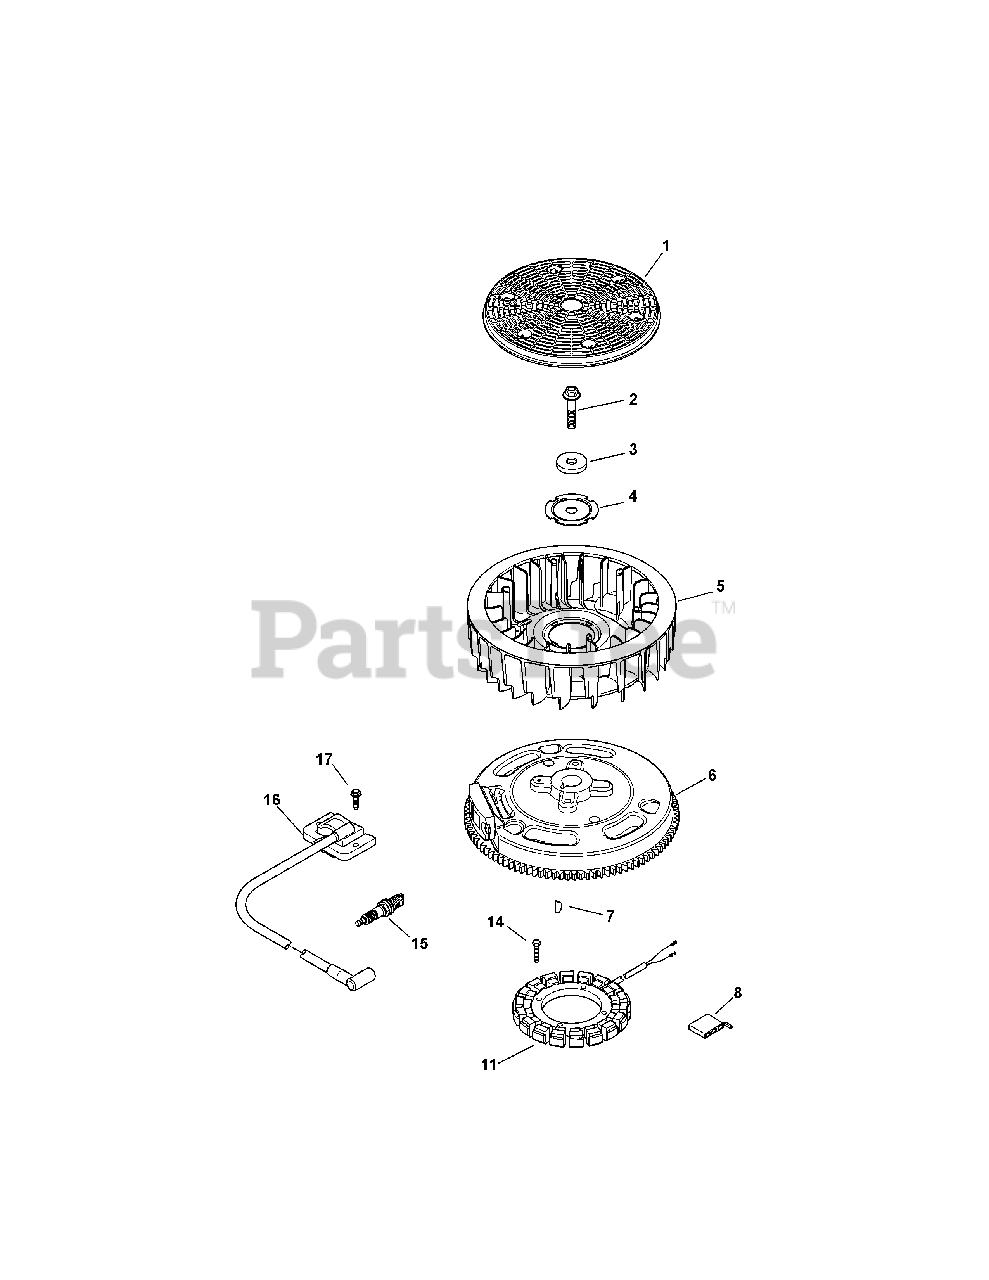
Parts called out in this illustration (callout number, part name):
2	Flg. Screw, M 10 X 1.5 X 45
3	Flat Washer, 13/32
4	Fan Mounting Plate
5	15 Amp Stator Kit (Inc. KH-25-452-01-S)
6	Flywheel Assembly
7	Key, 3/16 X 5/8
11	15 Amp Stator Kit
14	Thd. Frm. Screw, M5 X 0.8 X 25
15	Spark Plug
16	Module Ignition Kit
17	Flg. Thd. Frm. Screw, M5 X .8 X 20
